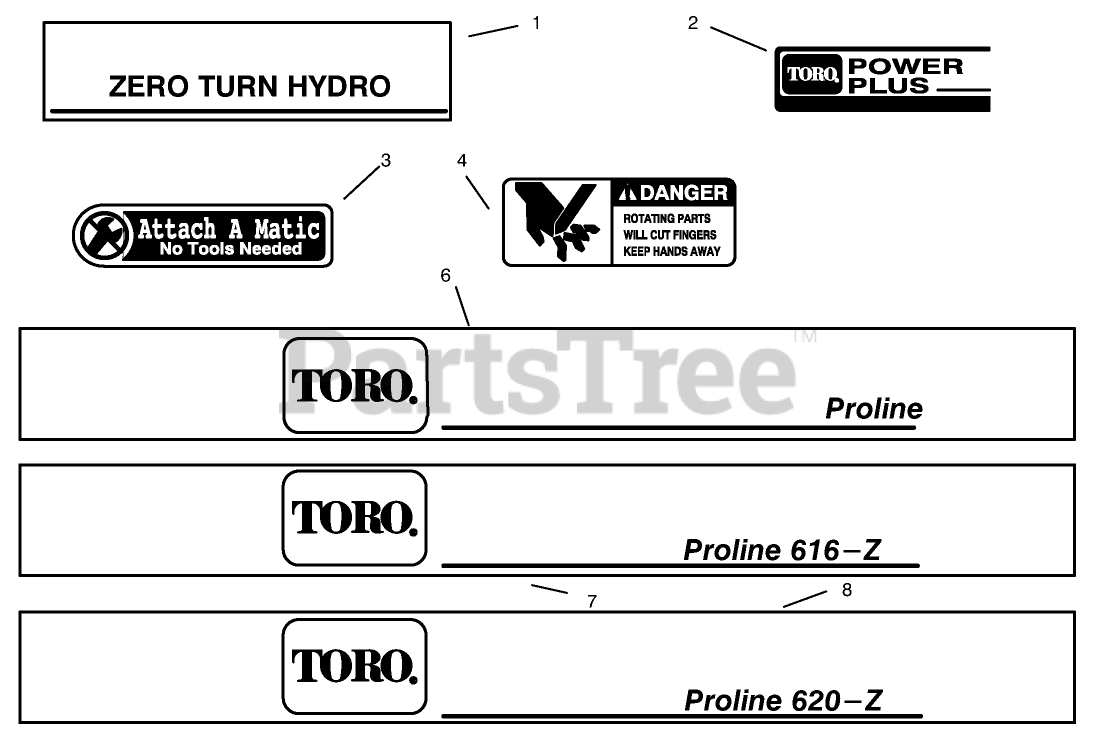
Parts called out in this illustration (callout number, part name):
1	DECAL-ZERO TURN HYD
2	DECAL POWER PLUS 16
3	DECAL-ATTACH A-MATIC
4	DECAL - DANGER
6	DECAL-TORO REAR
7	DECAL - TORO 616-Z
